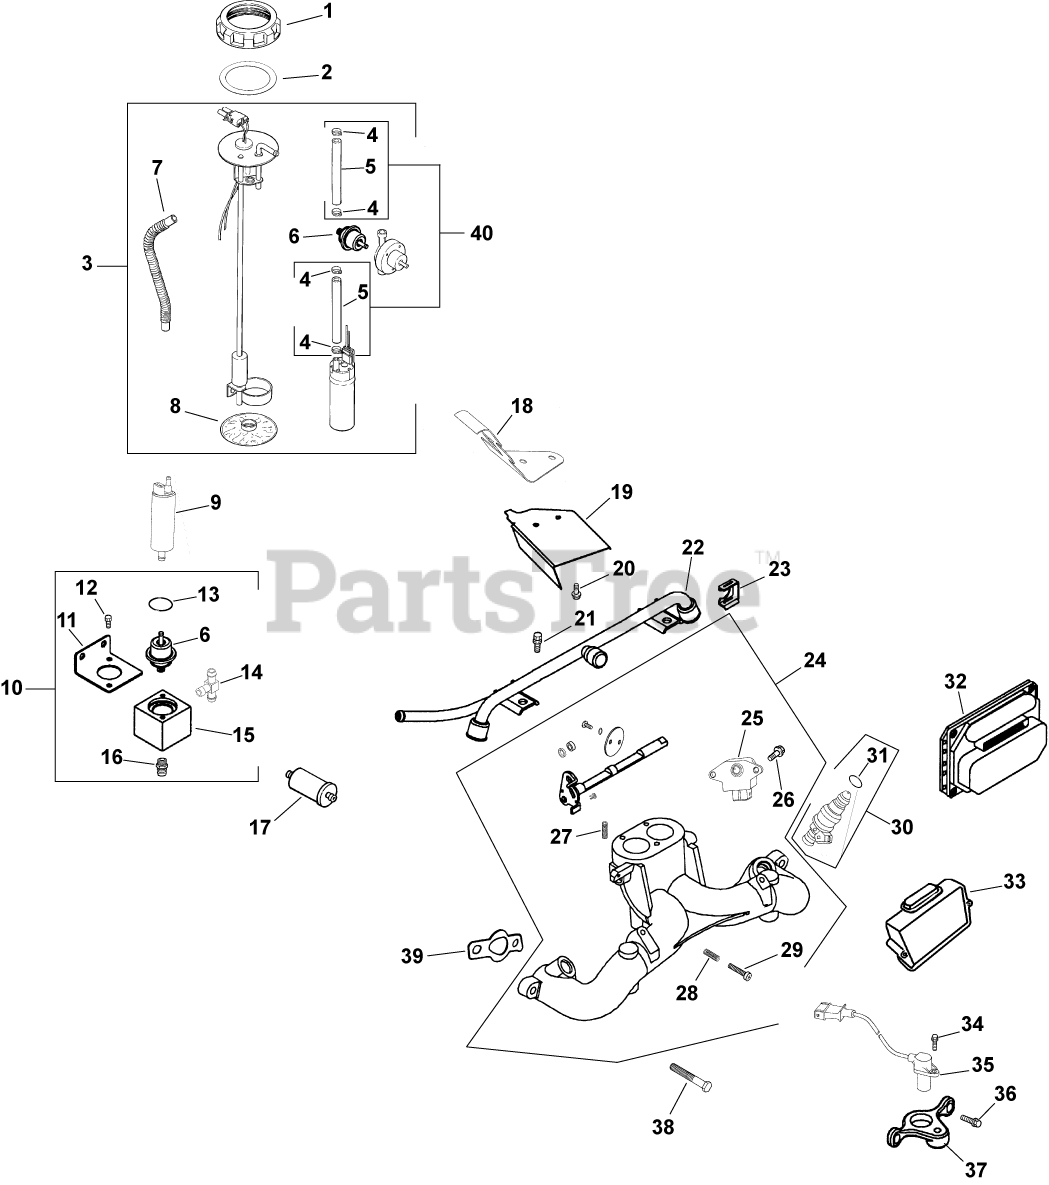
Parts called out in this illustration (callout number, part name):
6	REGULATOR, FUEL PRESSURE
8	FILTER, FUEL STRAINER
9	PUMP ASSY, FUEL-USE 24 393 52-S
10	REGULATOR ASSY, FUEL PRESSURE
11	BRACKET, REGULATOR -USE 24 403 16-S
12	SCREW, HEX HEAD MACHINE
14	REGULATOR ASSY, FUEL PRESSURE
15	LINKAGE, THROTTLE-USE 24 403 16-S
16	FITTING, BARBED - USE 25 294 16-S
17	FILTER, FUEL
18	BAFFLE, VALLEY
19	DEFLECTOR, AIR
20	SCREW, FLG THD FRM M5X.8X10
21	SCREW, FLG M6X1.0X10
22	KIT, FUEL RAIL
23	CLIP, FUEL INJECTOR
24	KIT, INTAKE MANIFOLD
25	KIT, THROTTLE POSITION SENSOR
26	SCREW, PHL PAN M4X0.7X12
27	SCREW, THD FRM 1/4-14X.75"
28	SPRING, SPEED CONTROL (SHORT)
29	SCREW, PHL PAN M4X0.7X25
30	INJECTOR, FUEL - DISCONTINUED
32	MODULE, ENG MANAGEMENT - DISC.
34	SCREW,FLG THD FRM M6X1.0X16-(#25086404S)
35	KIT, SPEED PICK-UP SENSOR
36	SCREW,FLG THD FRM M5X0.8X16-(#25086398S)
37	BRACKET, SPEED SENSOR-(#DSC)
38	SCREW,FLG M6X1.0X25 (#25086294S)
39	GASKET, INTAKE MANIFOLD USE 24 041 79-S
